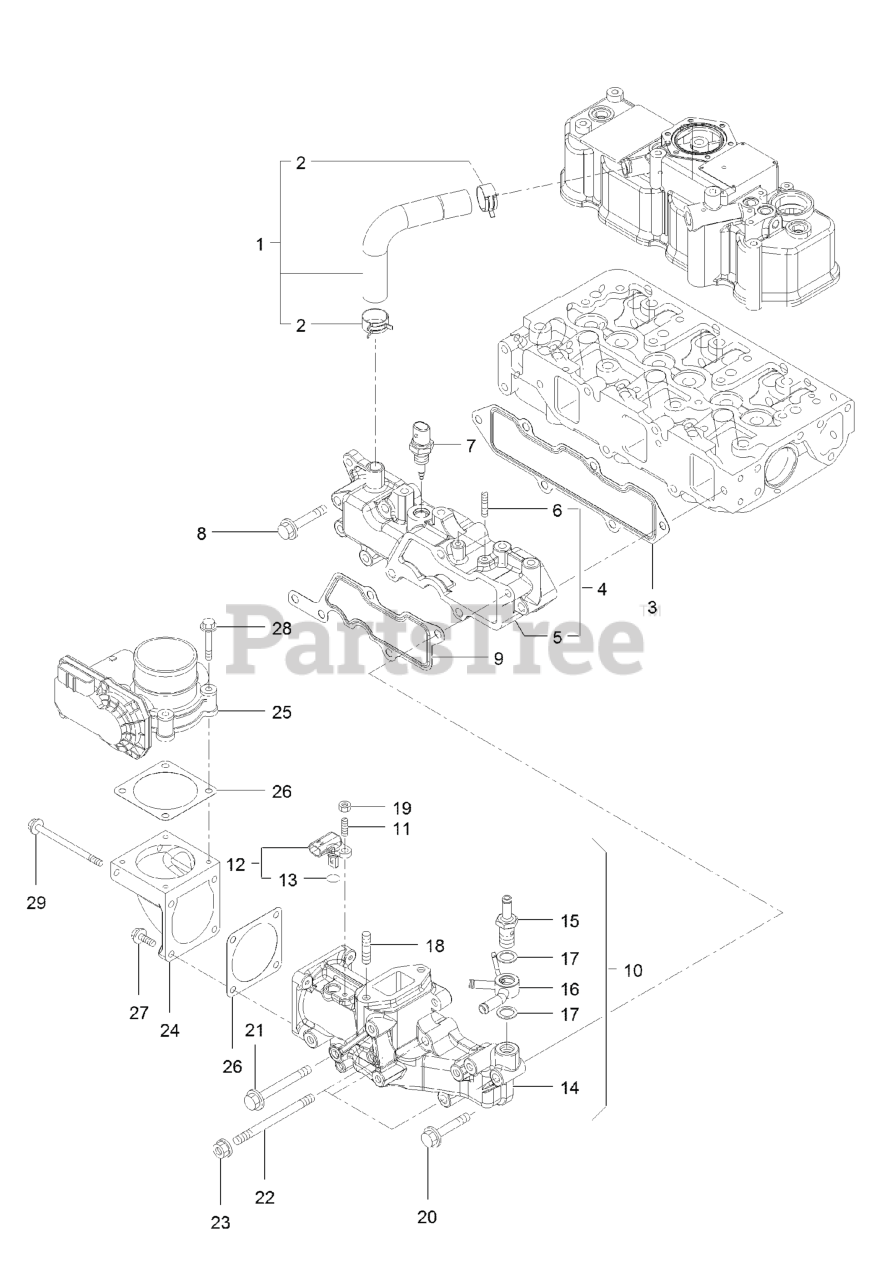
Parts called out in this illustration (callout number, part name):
2	CLIP-HOSE
3	GASKET-MANIFOLD, INTAKE
4	INTAKE MANIFOLD ASM
5	MANIFOLD-INTAKE
7	SENSOR-TEMP, AIR
9	GASKET-COLLECTOR
10	INTAKE COLLECTOR ASM
12	SENSOR-TEMP, AIR
14	COLLECTOR-INTAKE
15	JOINT-HOSE
16	Joint-Hose
17	Washer-Seal
24	Bend-Inlet
25	BODY-THROTTLE
26	GASKET-THROTTLE
